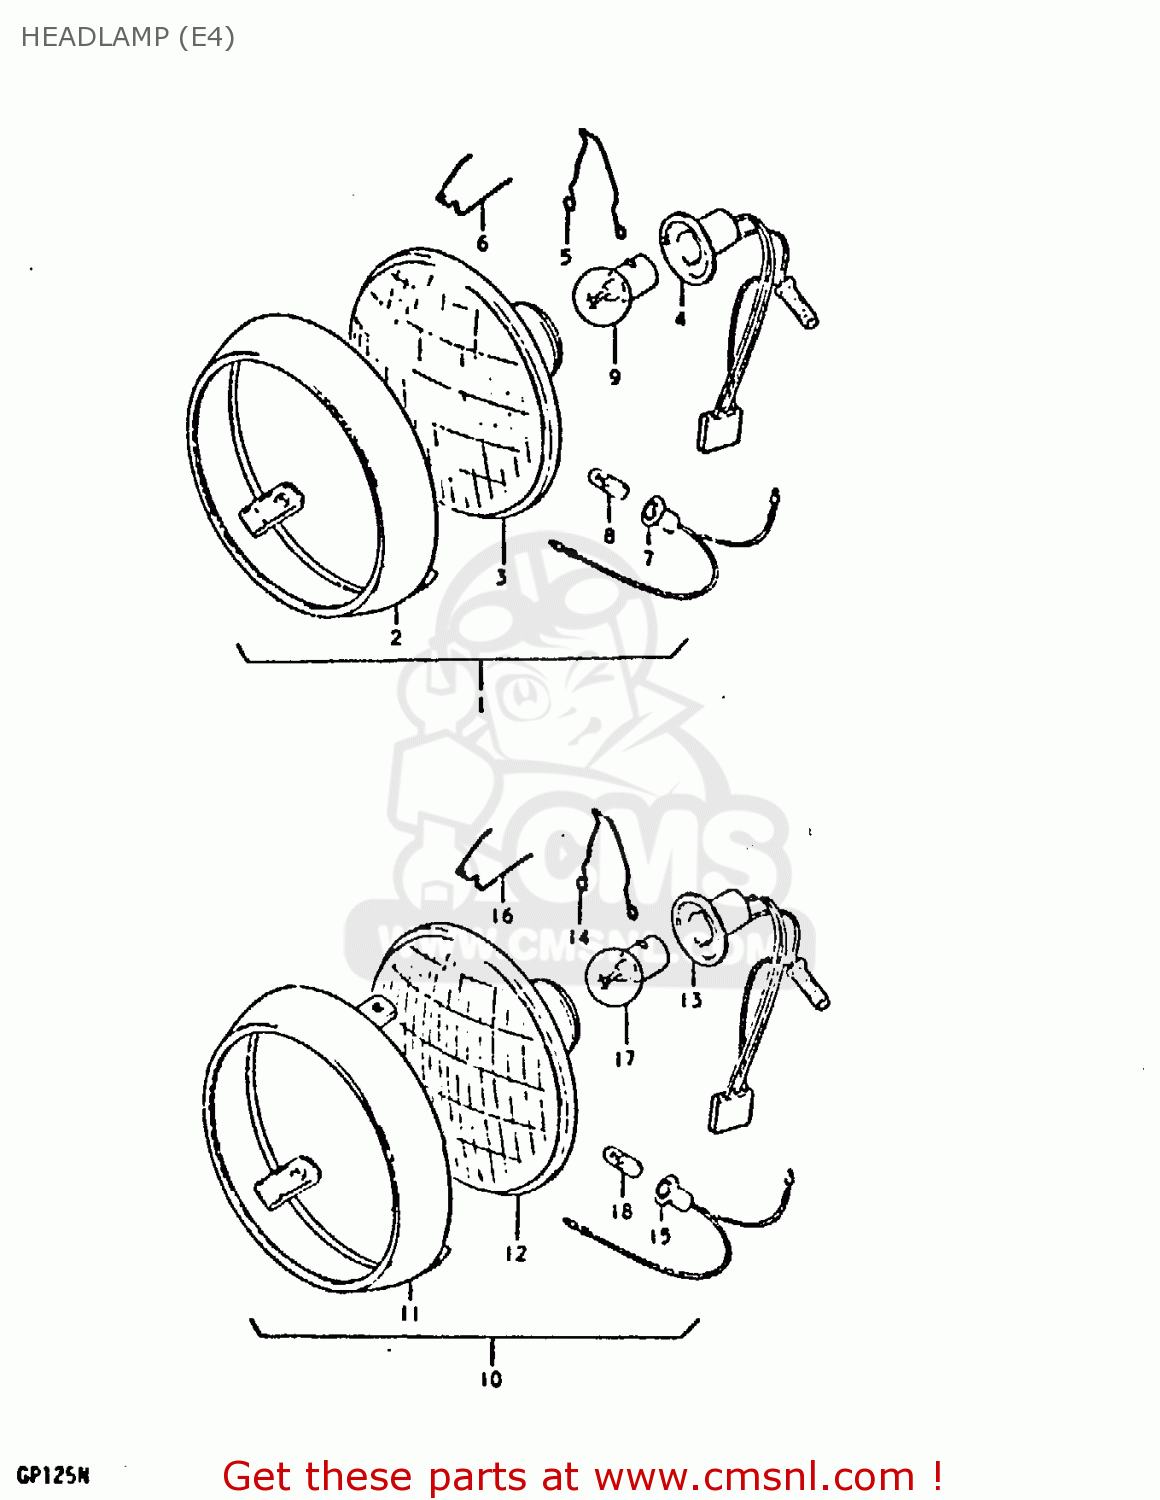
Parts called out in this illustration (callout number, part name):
10	HEADLAMP ASSY
11	RIM
12	UNIT
13	SOCKET
14	CLAMP,HEADLAMP
15	SOCKET
16	SPRING
17	BULB (6V,25/25W)
18	BULB (6V,4W)
